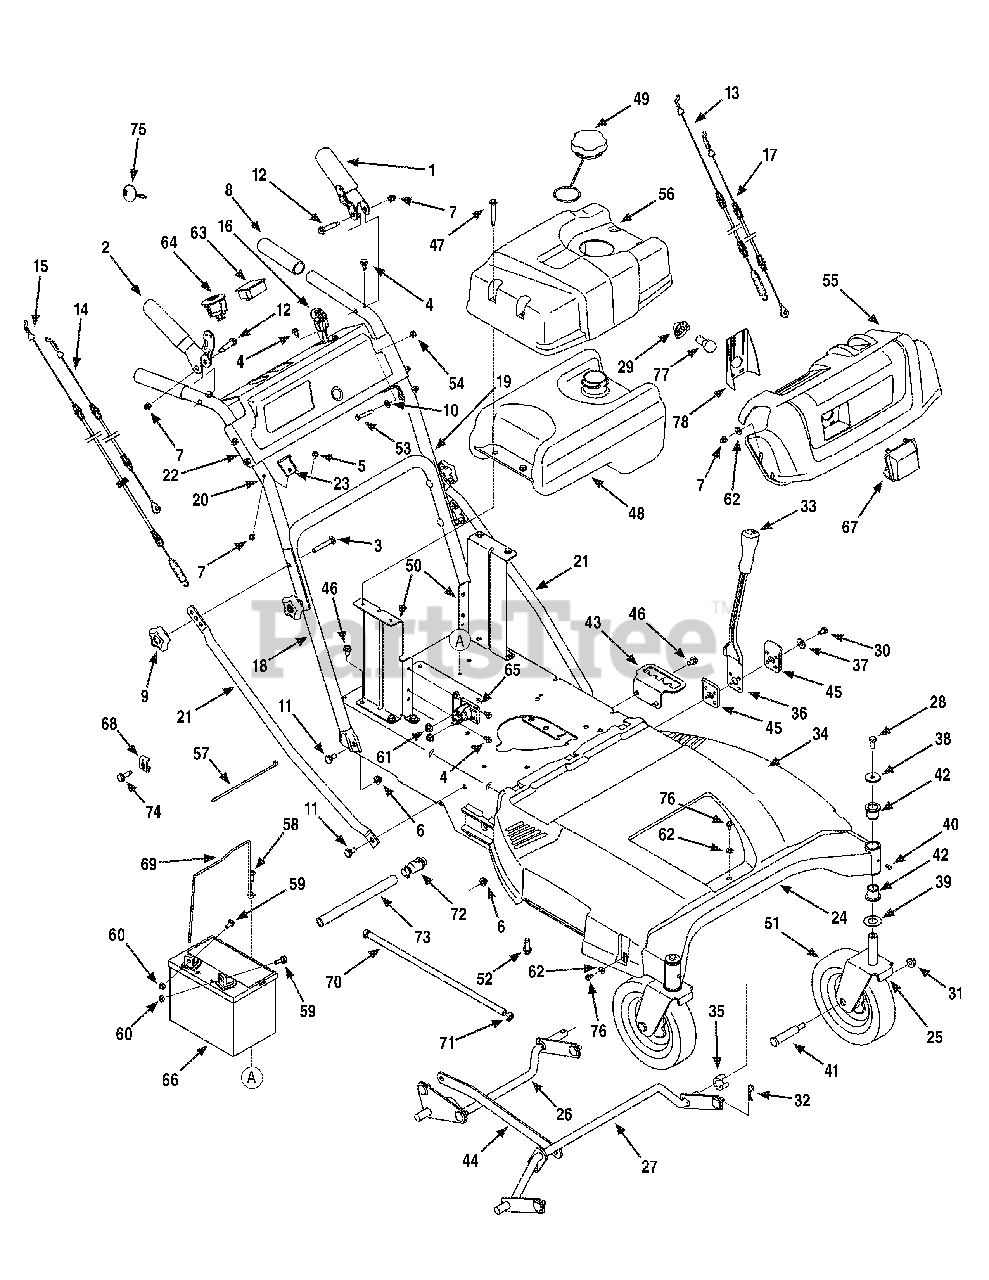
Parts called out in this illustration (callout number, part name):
1	Lever Assembly: LH
2	Lever Assembly: RH
3	Screw, Carriage: 5/16-18 x 2.25
4	Screw, 1/4-20 x 0.500
5	Screw, Cap: 1/4-20 x 1.50
6	Nut, Flange Lock: 5/16-18
7	Nut, Lock Cap: 1/4-20
8	Grip, 1.0 ID x 5.0 Lg
9	Star Knob 5/16-18
10	Washer, Bell: .265 x .75 x .062
11	Screw, Shoulder, .435 x .178-5/16
12	Screw, Shoulder, .375 x 1.355: 1/4-20
13	Cable, Clutch Wheel
14	Cable, Brake, Transmission: RH
15	Cable, Clutch Deck
16	Cable, Throttle/Choke: 38 x 1.1
17	Cable, Brake, Transmission: LH
18	Lower Handle
19	Upper Handle: LH
20	Upper Handle: RH
21	Brace Tube
22	Handle Panel
23	Cable Mount Bracket: RH
23	Cable Mount Bracket: LH
24	Frame Assembly
25	Caster Wheel Bracket Assembly
26	Deck Lift Assembly: RR
27	Deck Lift Assembly: Front
28	Screw, HH Cap: 5/16-24 x .750
29	Lamp Socket
30	Screw, HH Cap: 5/16-18 x .50
31	Nut, Flange Lock: 3/8-16
32	Click Pin: .092 x 1.64
33	Handle Grip 1/2
34	Belt Cover 33 Wide Cut Mower
35	Snap Spacer: .63 ID x .75 LG
36	Deck Height Lever
37	Washer, Bell: .340 x .872 x .060
38	Washer, Flat: .330 x 1.25 x .120
39	Washer, Flat: .760 ID x 1.50 OD
40	Lube Fitting: 3/16: LNC#70
41	Bolt, Shoulder: .625 x 2.515 x 3/8-16
42	Flange Bearing: .760 x .941 x 1.0
43	Height Adjustment Bracket
44	Link Pivot Bracket
45	Lever Pivot Bracket
46	Screw, TT: 5/16-18 x .625
47	Screw, Shoulder: .32 x 1.8 x 1/4-20
48	Fuel Tank, 2 Gal.
49	Fuel Cap
50	Fuel Tank Mounting Bracket
51	Wheel, 8 x 1.75
51	Flange Bearing, Wheel
52	Screw, TT: 3/8-16 x 1.25
53	Screw, HH Cap: 1/4-20 x 1.75
54	Nut, Hex: 1/4-20
55	Handle Panel
56	Tank Cover
57	Cable Tie
58	Screw, TT: 1/4-20 x .75
59	Screw, 1/4-20 x .75
60	Nut, Sems: 1/4-20
61	Nut, Flange Lock: 1/4-20
62	Washer, Flat: .25 x .63 x .0515
63	Hour Indicator Meter
64	Key Switch
65	Solenoid, 12V
66	Battery
68	Casing Clamp
69	Battery Hold Down
70	Fuel Hose
71	Hose Clamp
72	Oil Drain
73	Oil Drain Hose
74	Screw, 10-32 X .625
75	Key, Ignition, Black
76	Screw, 1/4-20 x 1.75
78	Label Reflector
